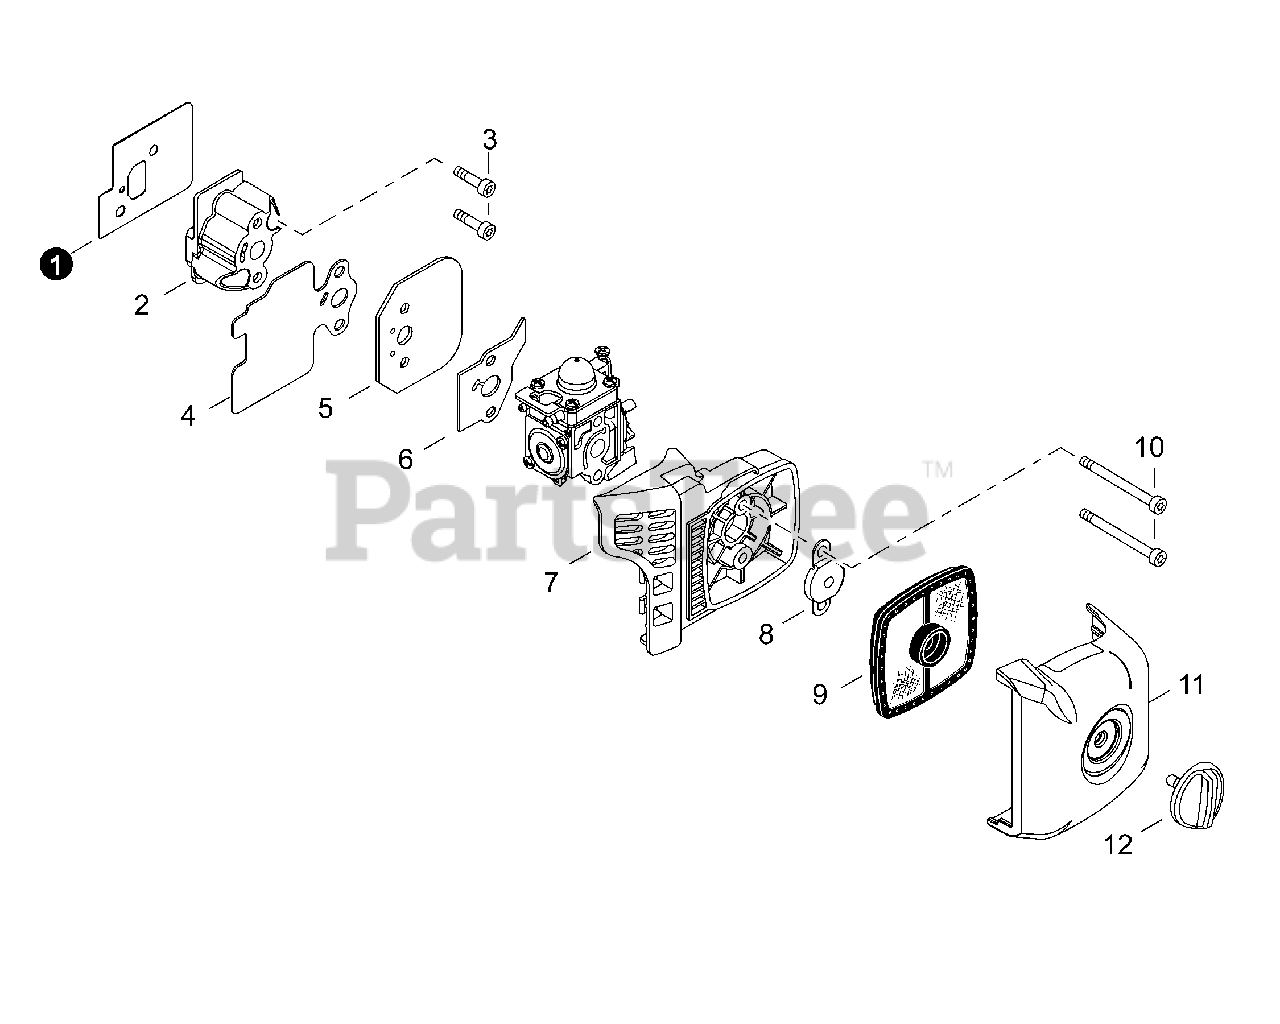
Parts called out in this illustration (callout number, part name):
1	GASKET, INTAKE
2	INSULATOR, INTAKE
3	BOLT, TORX 5×25
4	GASKET, INTAKE
5	PLATE, INSULATOR
6	GASKET, INTAKE
7	CASE, AIR FILTER
8	PLATE, PREVENT
9	FILTER, AIR - DOUBLE LAYER
10	BOLT, TORX 5×65
11	COVER, AIR FILTER
12	THUMBSCREW
